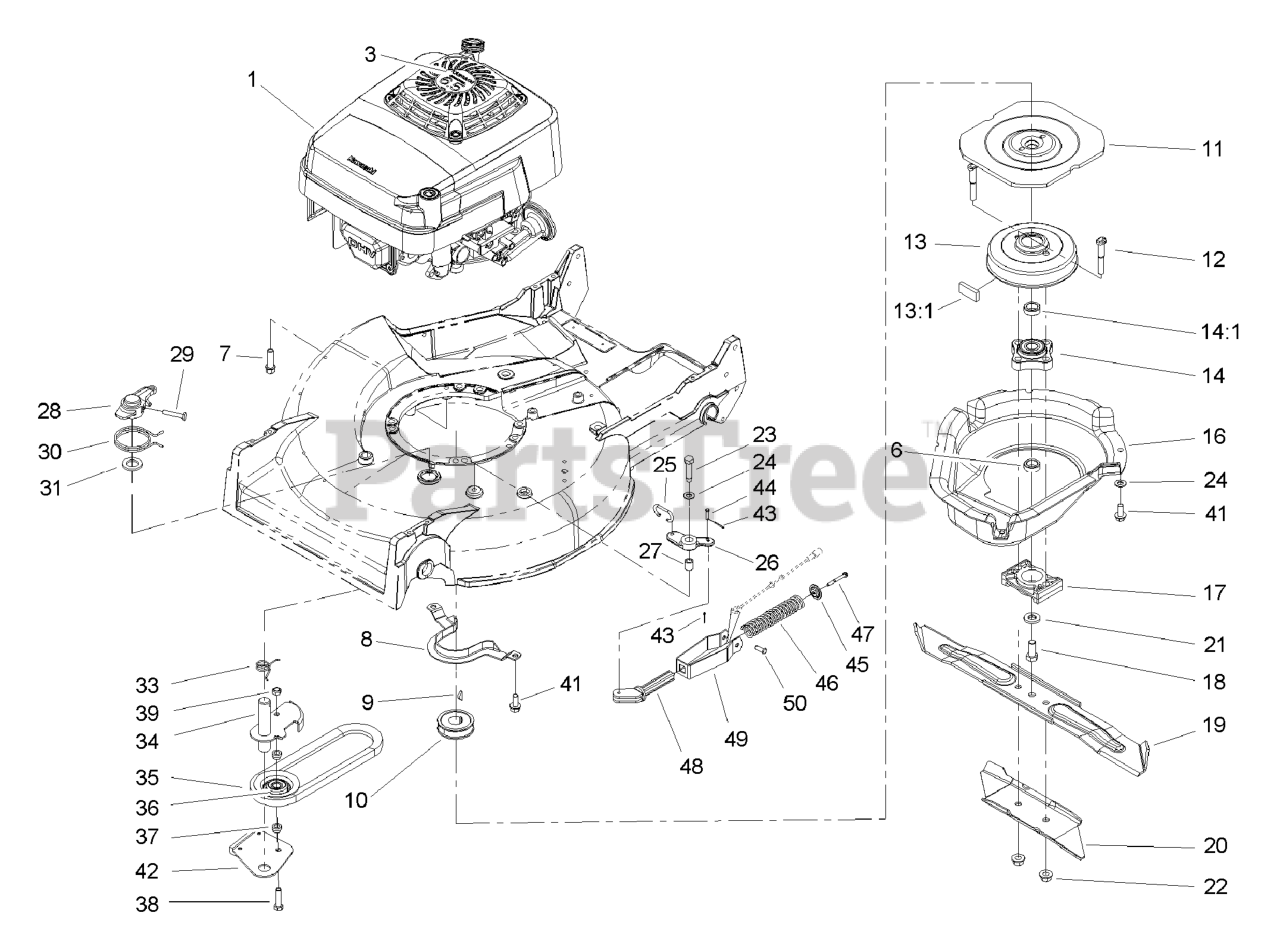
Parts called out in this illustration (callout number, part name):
3	Decal-Recoil
6	SPACER-SHAFT, OUTPUT
7	SCREW-TAPTITE
8	BRACKET-GUIDE, BELT
9	KEY-WOODRUFF
10	PULLEY-DRIVER
11	FLYWHEEL-BBC
12	BOLT-BLADE
13	BRAKE DRUM ASM
13:1	DAMPENER-VIBRATION
14	HUB ASM
18	SCREW-HH
20	STIFFENER-BLADE
22	Nut-Lock
23	SCREW-HH
24	WASHER-PLAIN
25	LINK-CONTROL
26	BELLCRANK
27	SLEEVE-BELLCRANK
29	SCREW-HH
30	SPRING-TORSION
33	SPRING-TORSION
34	ARM-IDLER
35	V-BELTNSP
37	SPACER-PULLEY, IDLER
38	SCREW-HH
39	NUT-LOCK, NI
41	Screw-HWH 5/16-18 X 3/4 Tf
43	PIN-COTTER
44	PIN-SPRING
45	RETAINER-SPRING
47	SCREW-HWHTF
49	BRACKET-SPRING
50	PIN-CABLE
